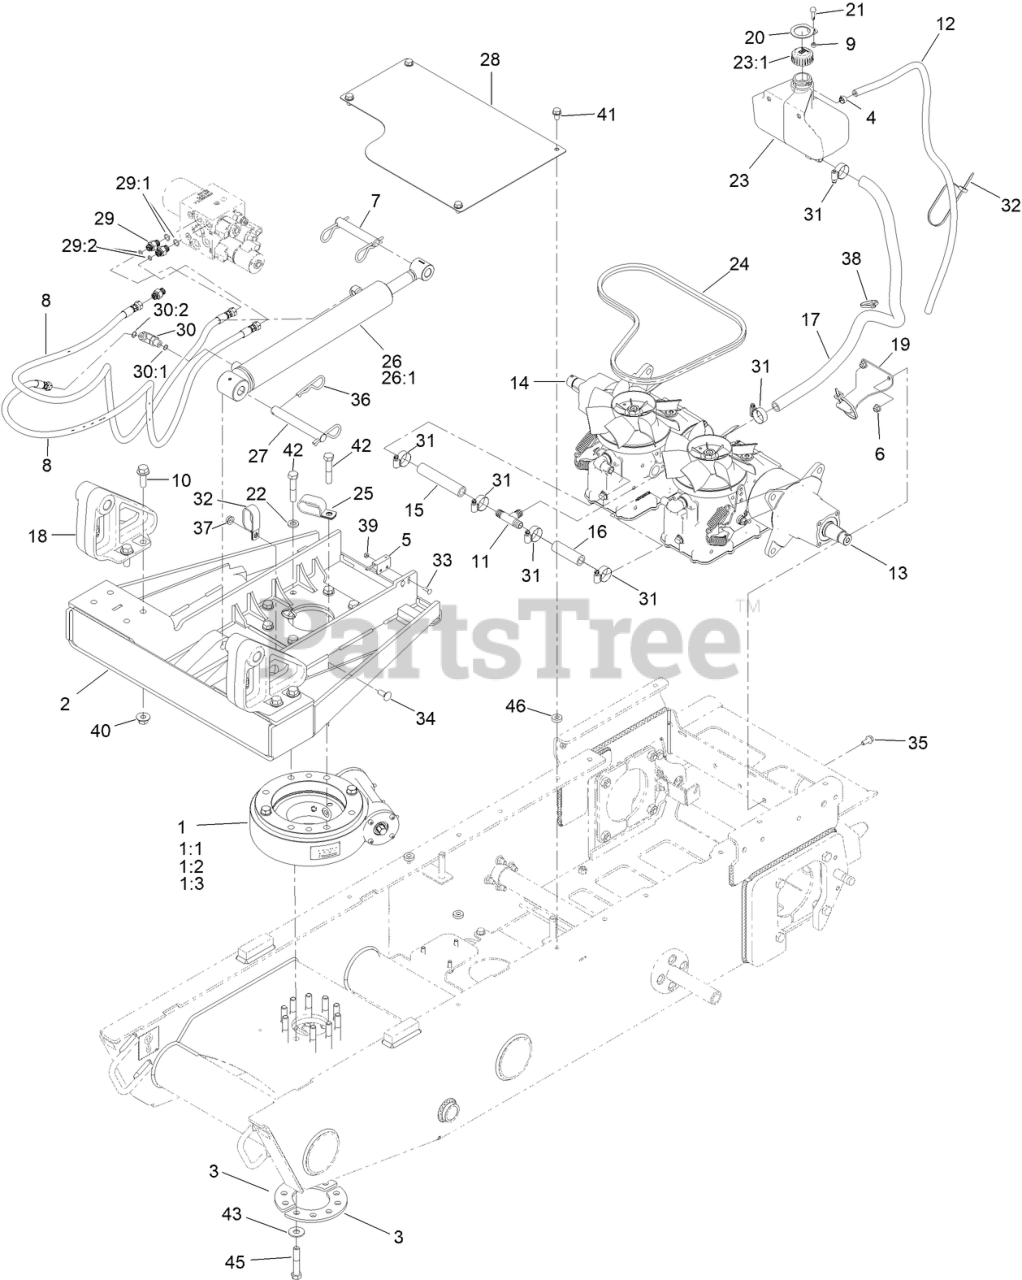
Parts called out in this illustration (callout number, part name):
1	DRIVE-SLEW
1:1	MOTOR-HYD, SLEW
1:2	SEAL-LIP
1:3	SEAL-TOP PLATE
2	TOP SWIVEL PLATE ASM [BLACK]
3	SPACER-SLEW MOUNT
4	CLAMP-HOSE
5	SWITCH-PROXIMITY
6	NUT-HF, NI
7	PIN-PIVOT
8	HOSE-HYD
9	SPACER
10	SCREW-HHF
12	HOSE-BREATHER, TRANSMISSION
13	LH HYDRO TRANSAXLE ASM
14	RH HYDRO TRANSAXLE ASM
15	HOSE-HYD, HYDRO
16	HOSE-HYD, HYDRO
17	HOSE-HYD, HYDRO
18	PIVOT-DUMP
19	BRACKET-HOSE RETAINER
20	LOCK-TANK
22	WASHER-THRUST
23	TANK-HYDRAULIC
23:1	CAP-VENTED
24	BELT-V
25	CLAMP-R, DOUBLE
26	CYLINDER, HYDRAULIC
27	PIN,PLAIN
28	SHIELD_COVER
29	FITTING-STRAIGHT
29:1	O-RING
29:2	O-RING
30	FITTING-ELBOW, 90 DEG
30:1	O-RING
30:2	O-RING
31	CLAMP-HOSE
32	CLAMP-R, DOUBLE
33	SCREW-CARR
34	BOLT-CARR
35	SCREW-HHF
36	PIN-HAIR
37	NUT-HHF, WHIZ
38	TIE-CABLE
39	NUT-LOCK, NI
40	NUT-LOCK, FLANGE
41	SCREW-HHFTF
42	SCREW-HH
43	WASHER-FLAT
45	SCREW-HH
46	SPACER
